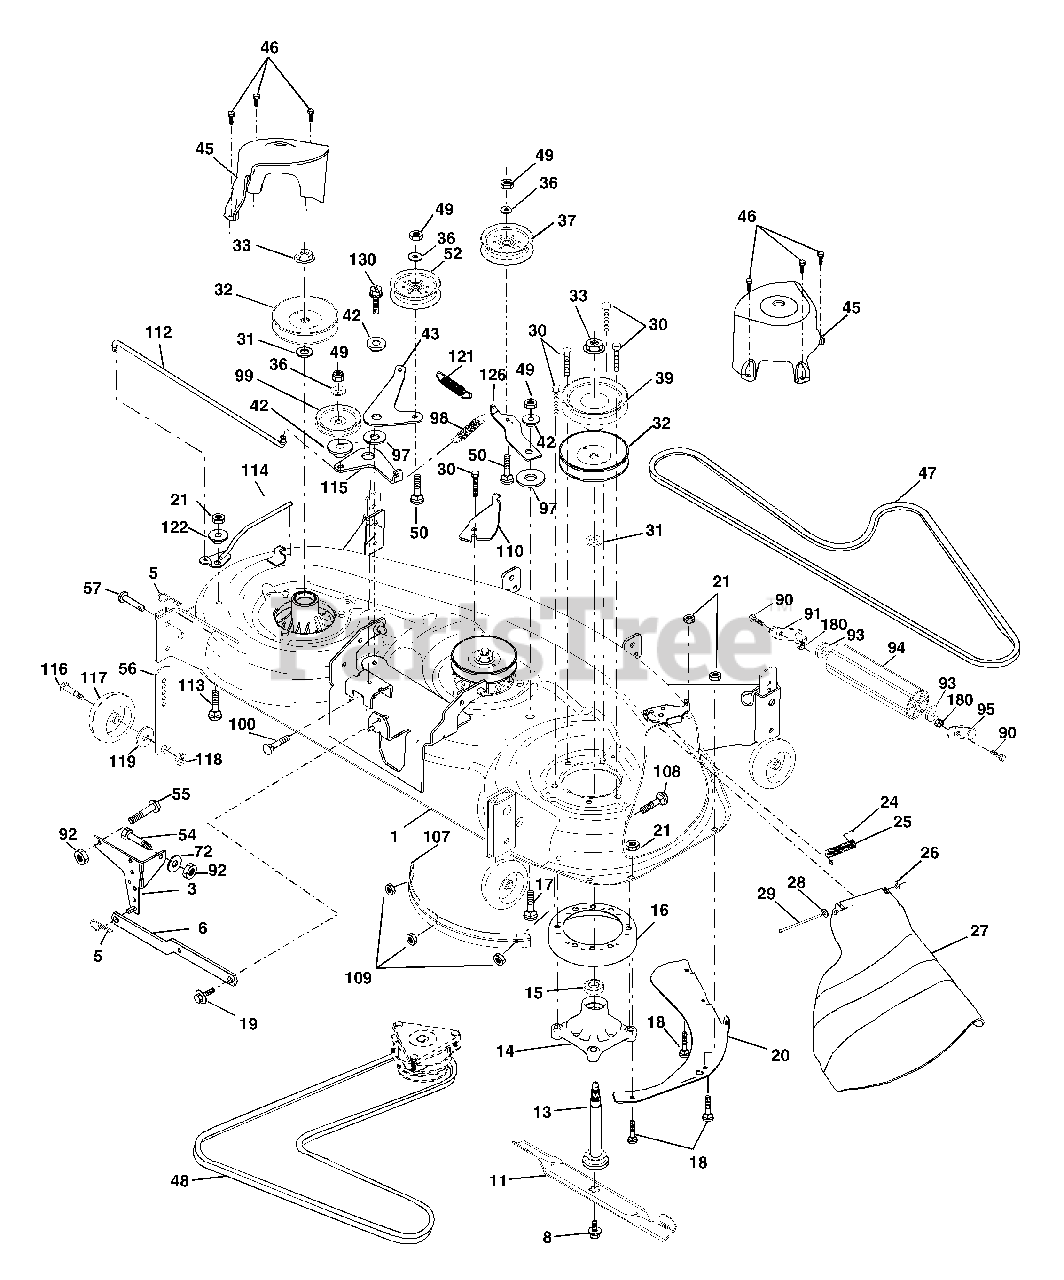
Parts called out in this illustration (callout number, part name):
1	Deck Weldment Mower 48
3	Bracket Asm., Sway Bar
5	Retainer Spring
6	Arm, Suspension, Rear (Sway Bar)
8	Bolt, 7/16 Asm. Blade
10	Washer, Hard Blade, Mower Vented
11	Blade
13	Shaft Asm. greaseable
14	Housing Mandrel 48"
15	Bearing, Ball, Mandrel
16	Stripper, Mower
17	Bolt Rdhd Sq Neck 3/8-16 x 1.25
18	Bolt, Carriage 5/16-18 x 5/8
19	Bolt, Hex Head, Shoulder 5/16-18
20	Baffle, Vortex Mower
21	Nut, Crownlock 5/16-18 UNC
24	Cap, Sleeve
25	Spring, Torsion
27	Shield, Deflector Mower
28	Washer 11/32 x 5/8 x 16 Ga.
29	Rod, Hinge
30	Screw, Thdroll, Washer Head
31	Washer, Spacer Mower Vented
32	Pulley, Mandrel
33	Nut, Flg. Top Lock Cntr. 9/16
36	Washer 13/32 x 13/16 x 16 Ga.
37	Pulley, Idler, Flat
39	Pulley, Idler, Driven
42	Spacer, Retainer
43	Arm, Idler Secondary
45	Cover, Mandrel Deck
46	Screw, Thdroll. 1/4-20 x 5/8
47	V-Belt, Mower, Secondary
48	V-Belt, Mower, Primary
49	Nut, Crownlock 3/8-16 UNC
50	Bolt, Carriage 3/8-16 x 1-1/2 Gr. 5
52	Pulley Idler Flat 46 Pri. Drive
54	Bolt Fin Hex 3/8-16 x 1
55	Bolt Rdhd Sqnk 3/8-16 x 1
56	Bar Pnt Adjusting Wheel Gauge
57	Pin Head Rivet
72	Washer 13/32 x 13/16 x 12
90	Bolt, Fin, Hex 5/16-18 x 1.0
91	Bracket, Asm Noseroller, LH 48
92	Nut Lock Hex w/Ins 3/8-16
93	Washer 17/32 x 7/8 x 16 Ga.
94	Roller, Nose 48"
95	Bracket, Asm Noseroller RH 48
97	Washer Hardened
98	Spring Primary Drive
99	Pulley Idler "V"
100	Bolt RDHD Sqnk 3/8-16 Unc x 2
107	Baffle Vac Edge Mower
108	Bolt Carr.
109	Nut Crownlock 1/4-20
110	Arm Spring Secondary
112	Link Tension Relief Lever
113	Bolt Carr. 5/16-18 x 1
114	Tension Asm Relief Lever
115	Arm Spring Tension Relief
116	Bolt, Shoulder
117	Gauge Wheel
118	Nut, Centerlock 3/8-16 UNC
119	Washer 3/8 x 7/8 x 14 Ga.
121	Spring Secondary Drive
126	Arm, Idler, Primary Deck
130	Screw 3/8-16 x 1.0
180	Nut, Lock, Hex 5/16-18
